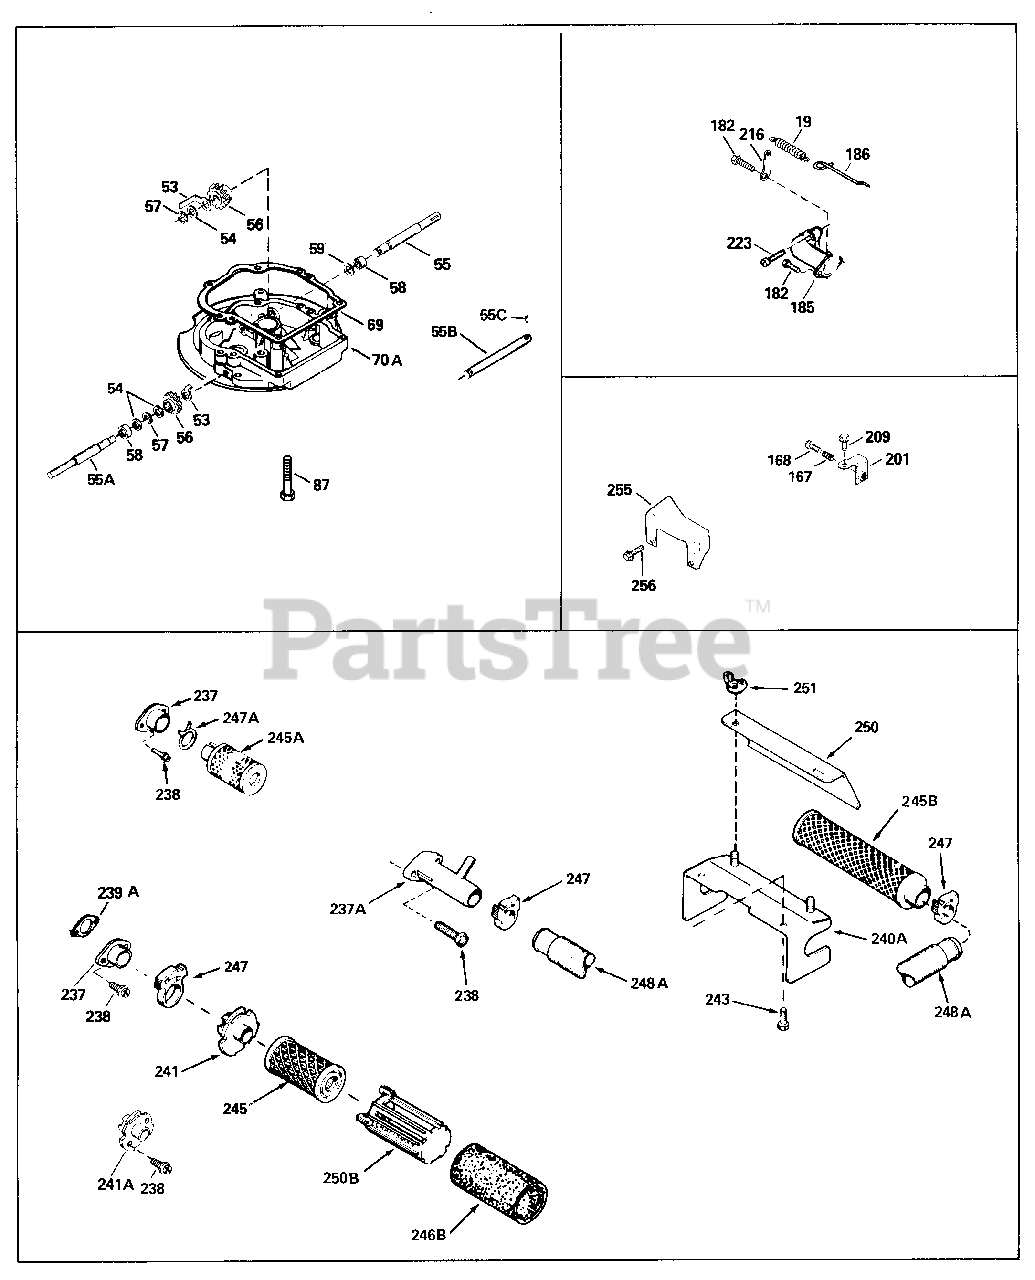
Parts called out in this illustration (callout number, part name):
19	Spring, Extension
69	* Gasket, Mounting flange
182	Screw, 1/4-28 x 7/8"
185	Pipe, Intake (Incl. 224)
186	Link, Governor spring
216	Lever, Speed adjusting
223	Screw, 1/4-20 x 1"
238	Screw, 10-32 x 5/8"
246B	Filter, Pre-Air (Use as required)
